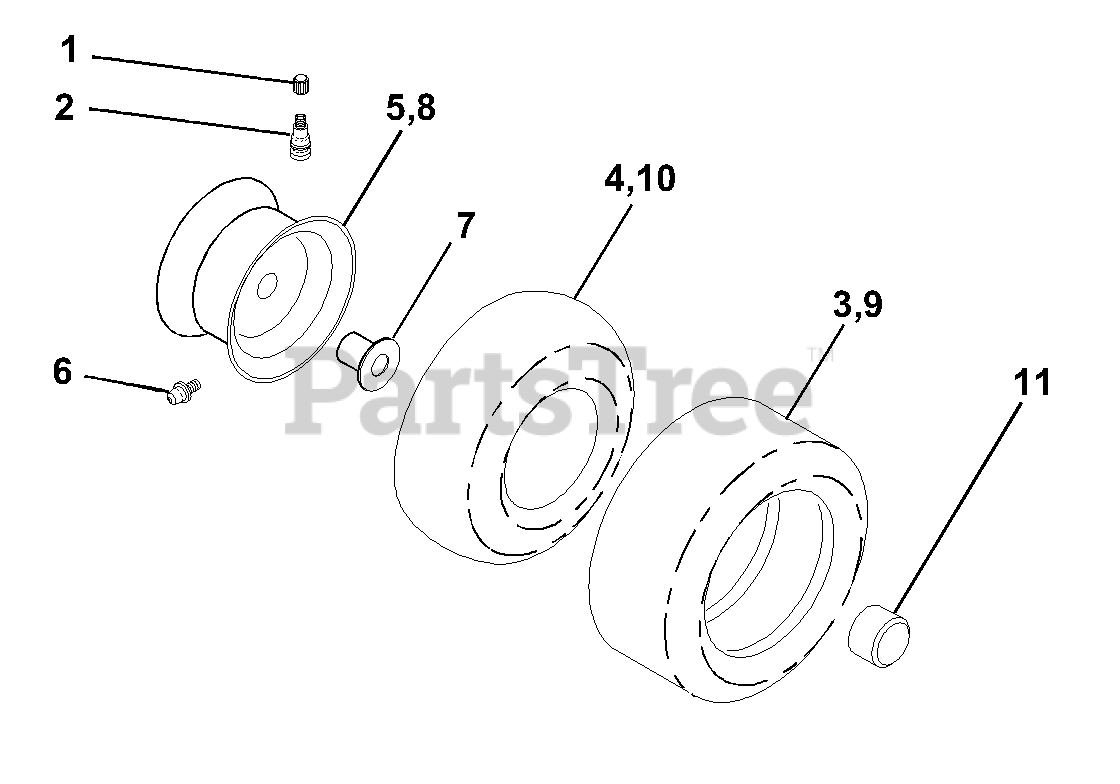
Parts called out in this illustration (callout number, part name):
1	Cap Valve Tire
2	Stem Valve
3	Tire F T 15 X 6 0 - 6 Service
4	Tube Front
5	Rim Asm 6" front Service
6	Fitting Grease
7	Bearing Flange
8	Rim Asm 8" rear Service
9	Tire R T 20x10-8 Service
10	Tube Rear
11	Cap Axle Blk 1 50 X 1 00
